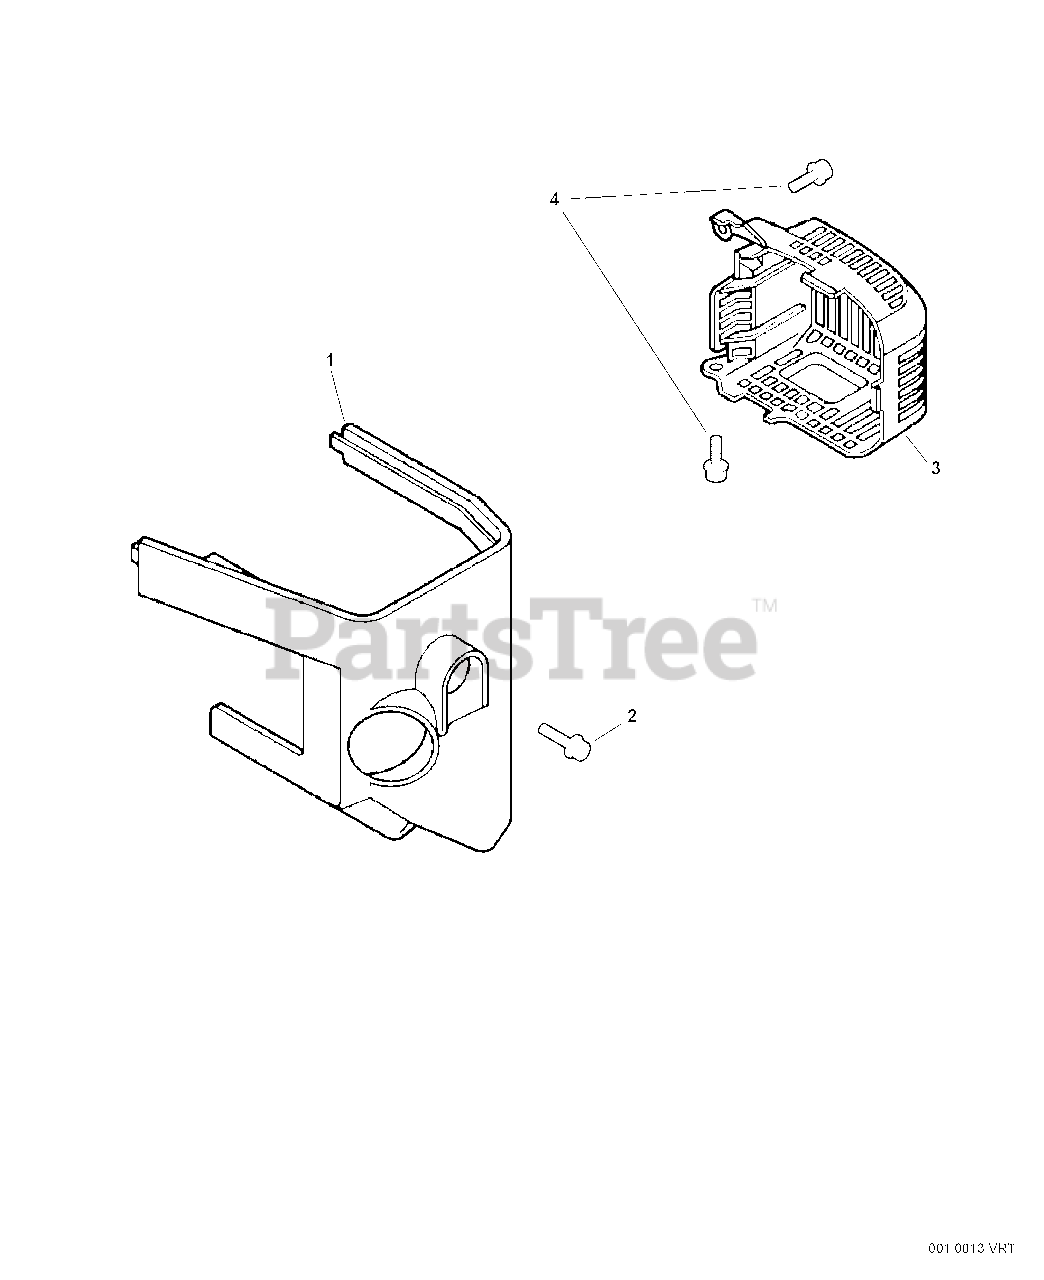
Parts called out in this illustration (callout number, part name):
1	COVER, ENGINE
2	BOLT 5×12
3	COVER, MUFFLER
4	BOLT 5×16
